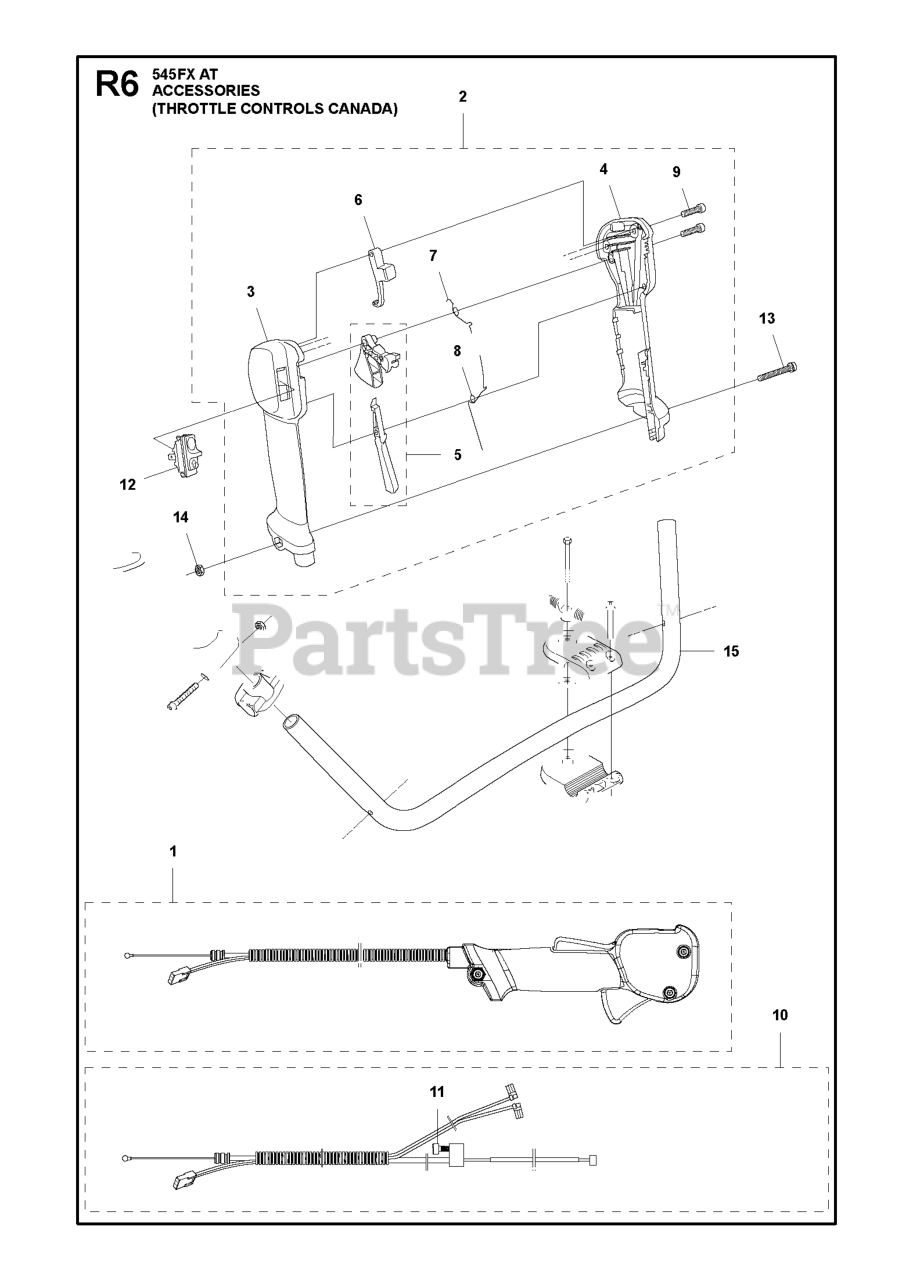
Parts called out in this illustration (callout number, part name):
2	THROTTLE HANDLE ASSY HVA, SPA
3	HANDLE HALF LEFT
4	HANDLE HALF RIGHT
5	THROTTLE CONTROL
6	BUTTON BLIND BUTTON
9	SCREW IHSCT MT4X18 10.9 ZN/FE
12	STOP BUTTON
13	SCREW IHSCFM
